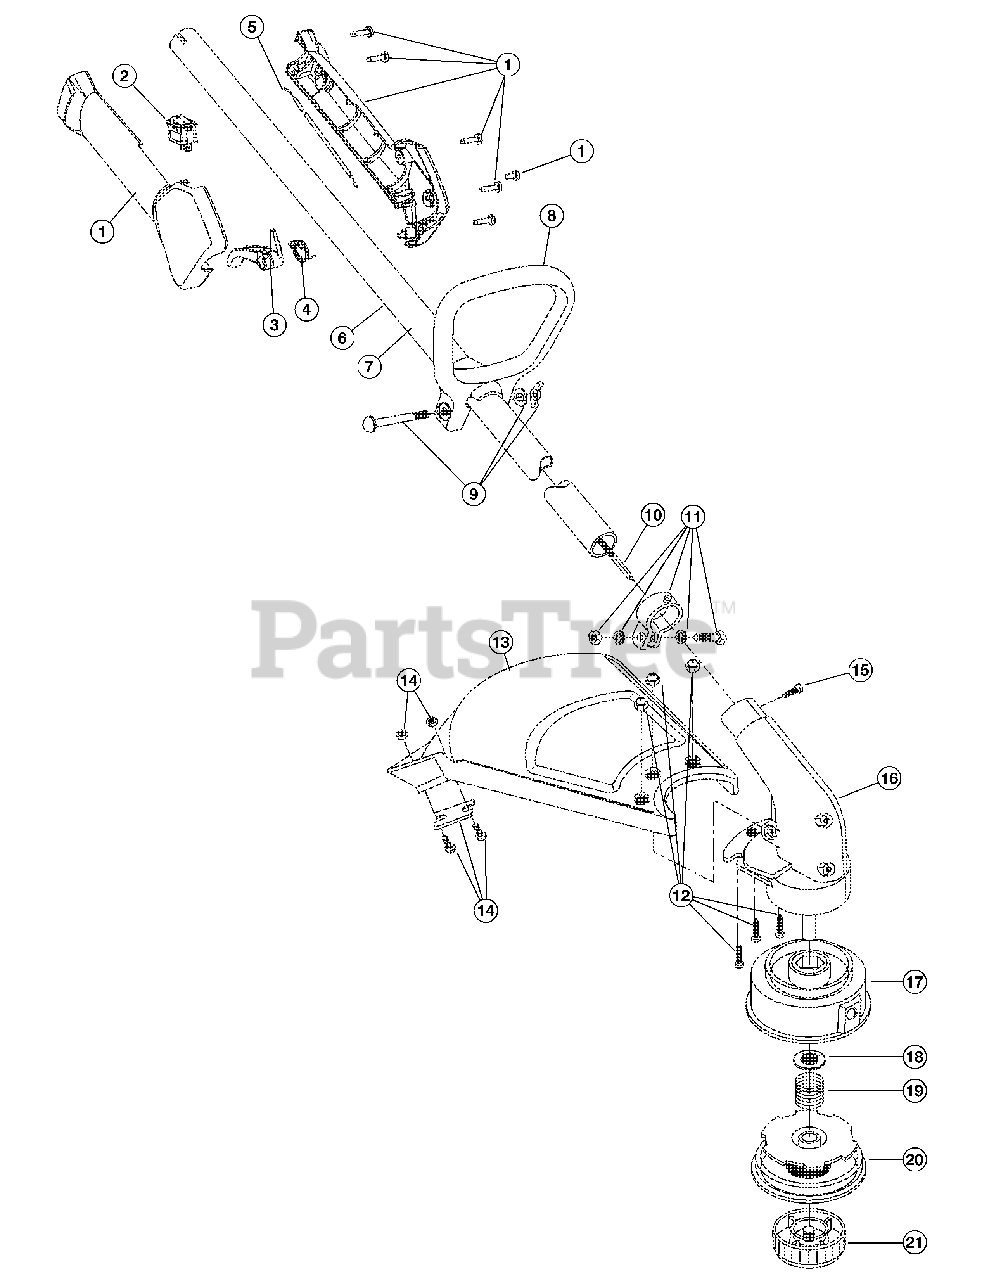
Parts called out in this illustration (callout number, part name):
1	Throttle Housing Assembly (includes 2-4)
3	Throttle Trigger
4	Throttle Trigger Spring
5	Throttle Cable
6	Harness Clip
7	Drive Shaft Housing Assembly
8	D-Handle (includes 9)
9	D-Handle Hardware Assembly
10	Flexible Drive Shaft
11	Lower Clamp Assembly (includes 13)
12	Guard Mounting Screw Assembly
13	Guard and Blade Assembly
14	Blade Assembly
15	Anti-Rotation Screw
16	Gearbox Assembly (includes 15 & 16)
17	Outer Spool Assembly
18	Retainer (10 pack)
20	Inner Reel
21	Bump Head Knob Assembly
